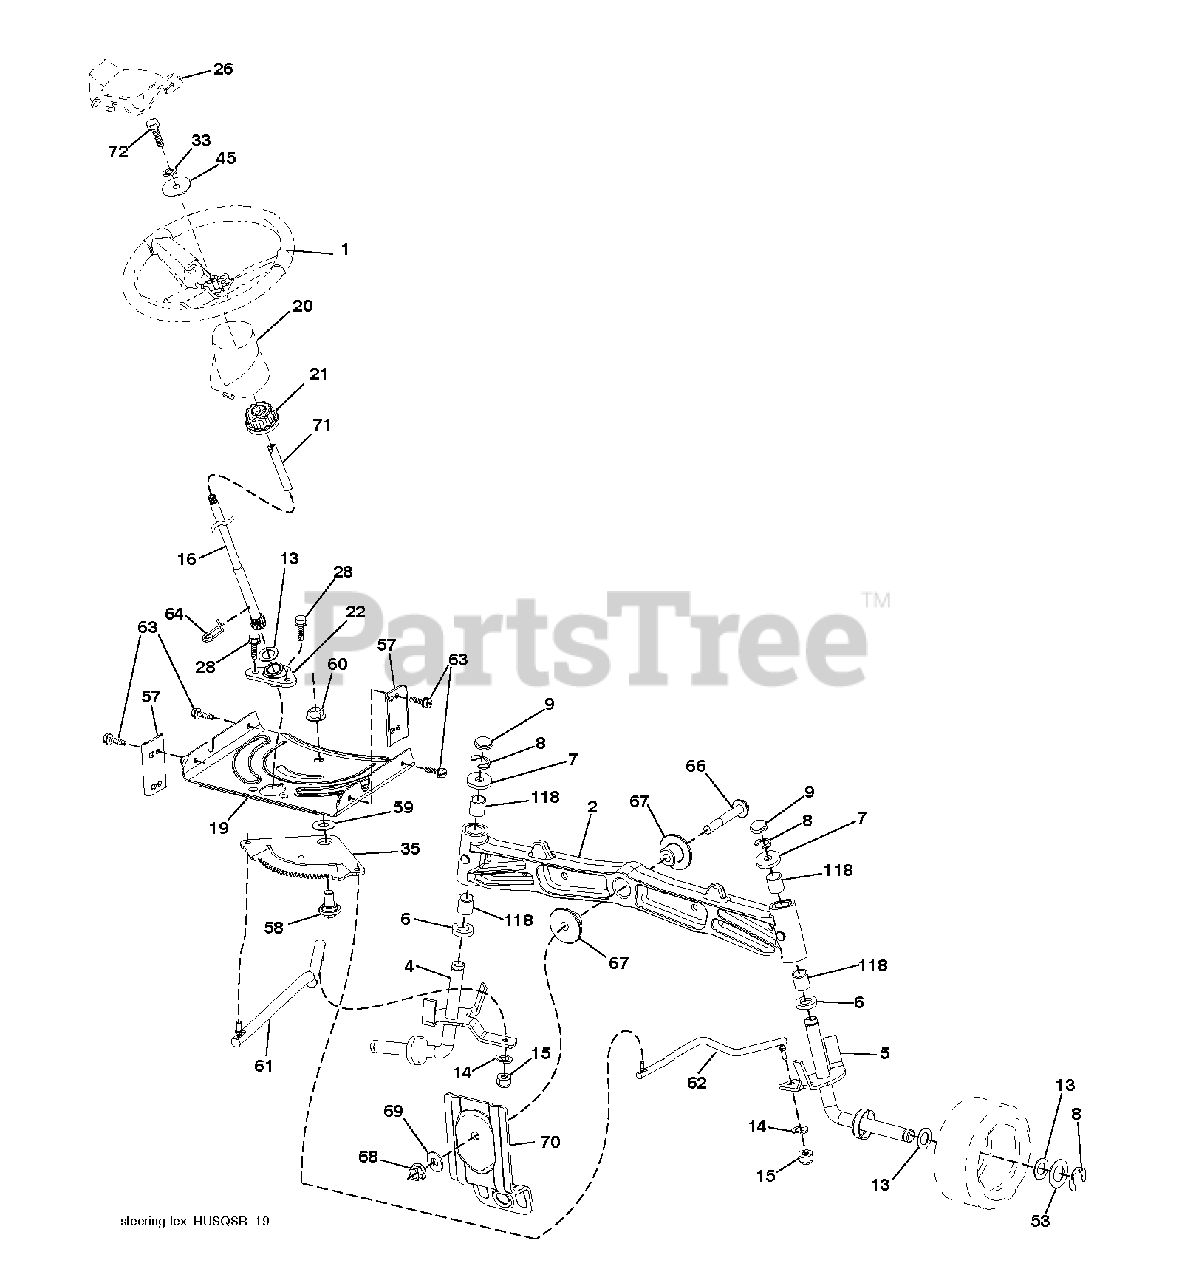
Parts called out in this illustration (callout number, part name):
1	WHEEL.STEERING.STDSRR.BLK/OV
2	AXLE.SVC.ASM CAST IRON.TEX
4	SPINDLE.WELDED.LH.15"TEX
5	SPINDLE.WELDED.RH.15"T
8	RING CLIP
9	CAP.SPINDLE
14	WASHER, LOCK 3/8
15	NUT CROWNLOCK 3/8-24
16	SHAFT.STEER.3/4.PLATED.TEX
19	PLATE.STEER.DDL.NLT/NG
20	BOOT STEERING BLACK
21	ADAPTER, WHEEL STNG..
22	STEERING.SUPT.LOWER.
26	CAP.WHL.STRNG.STDSRRD.SRS.BLK
28	SCREW, 3/8-16X3/4
33	LOCKWASHER
35	GEAR.SECTOR.PLATE.DDL.
45	WASHER.11/32
53	WASHER.HARDENED
57	BRACKET.UPSTOP.TEX
58	BOLT.SHOULDER.SECTOR.P
59	WASHER.THURST.SECTOR.S
60	NUT FLANGE LOCK 5/8-11
61	DRAGLINK.LH.BALLSTUD.D
62	DRAGLINK.RH.BALLSTUD.D
63	SCREW
64	RETAINER.CLIP.SPRING.S
66	BOLT HEX FGHD 7/16-14 X 3 SERR
67	BUSHING.PM.FRONT AXLE
68	NUT.LOCK.FLANGE.7/16
69	WASHER.1.5X.505X.118
70	BRKT.DECK.SUSPENSION.F
71	SHAFT.EXTEN.STRG.SPLINE
72	BOLT 5/16-18 X 4 W/PATCH
118	BUSHING, AXLE CAST
